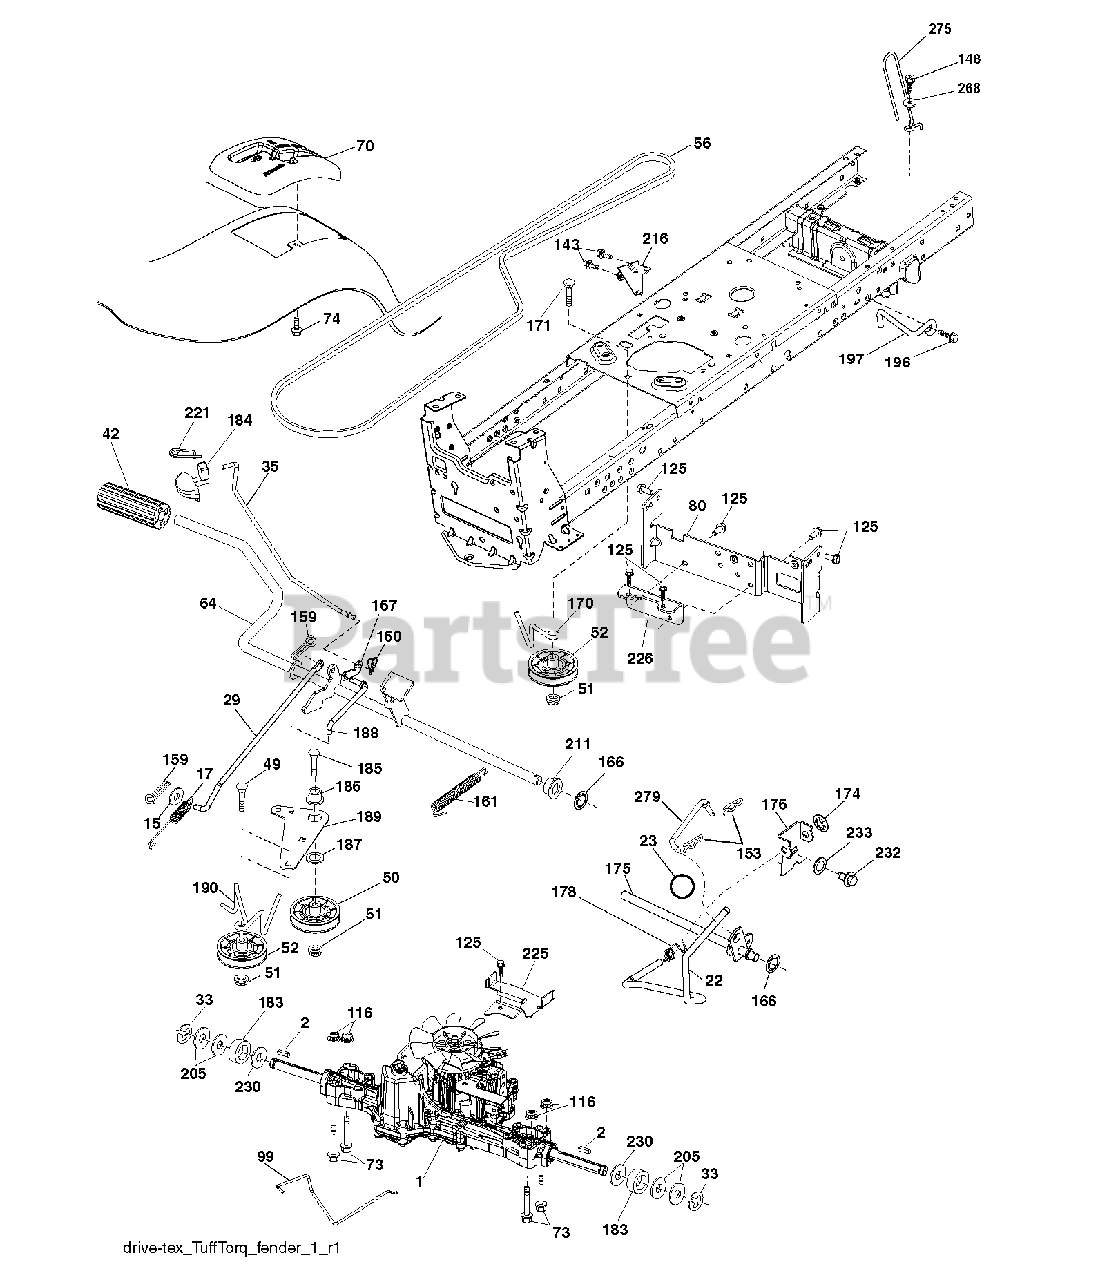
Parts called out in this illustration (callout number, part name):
2	SQUARE KEY
17	SPRING.BRAKE.K46.GREEN
22	ROD.SHIFT.FENDER.TLT.2006
23	PISTOL KNOB
29	ROD.BRAKE.K46
33	E-RING LT
35	ROD.BRAKE.PARKING.GT.H
42	PEDAL COVER T
49	BOLT
50	IDLER.FLAT.910.OFFSET
51	NUT LOCK FLG 3/8-16 UNC
52	IDLER.V-GROOVE.910.OFFSET
64	SHAFT.ASM.PEDAL.BRAKE.
70	CONSOLE.SHIFT.STL.HYD.BLACK
73	BOLT HEX 5/16-18 GR 5
74	SCREW.HI-LO.CONSOLE
80	STRAP TORQUE.ASM.K46/18"TEX
99	ROD.SPRING.BYPASS.K46.LT.Z
116	NUT LOCK HEX FLANGE 5/16-18
125	SCREW
148	SCREW, 3/8-16X3/4
153	RETAINER M
159	COTTER PIN
160	RETAINER CLIP
161	SPRING, RETURN LT
166	NUT.PUSH.625.2006
167	LATCH.BRAKE.SPRING
170	KEEPER.V-IDLER.CENTER.
171	BOLT
174	NUT.PUSH.500.2006
175	SHAFT ASM SHIFT
176	ARM.CLEVIS.ROD.SHIFT
178	SPRING.SHIFT.GT2006
183	SPACER AXLE
184	HANDLE.PARKG.BRK.HUSQ/
186	SPACER.RETAINER
187	WASHER 12/32X2X10GA
188	LINK.CLUTCH.GROUND.DRIVE
189	BELLCRANK.GROUND.DRIVE.TEX.
190	KEEPER.BELLCRANK.DRIVE
196	SCREW 3/8-16X1
197	LINK.CLUTCH.ANIT-ROTAT
211	BUSHING.SHAFT.BRAKE.HAND
216	BRACKET.PULLEY.IDLER.W/TEX
221	RETAINER.SPRING.CLIP.H
225	KEEPER.BELT.TRANSAXLE.K46
226	BRACKET.MOUNT.TORQUE.K46.TLT
230	WASHER.HARDENED
232	BOLT FIN HEX 7/16-14 X 1
233	WASHER SERRATED
268	WASHER
279	LINK SHIFT
